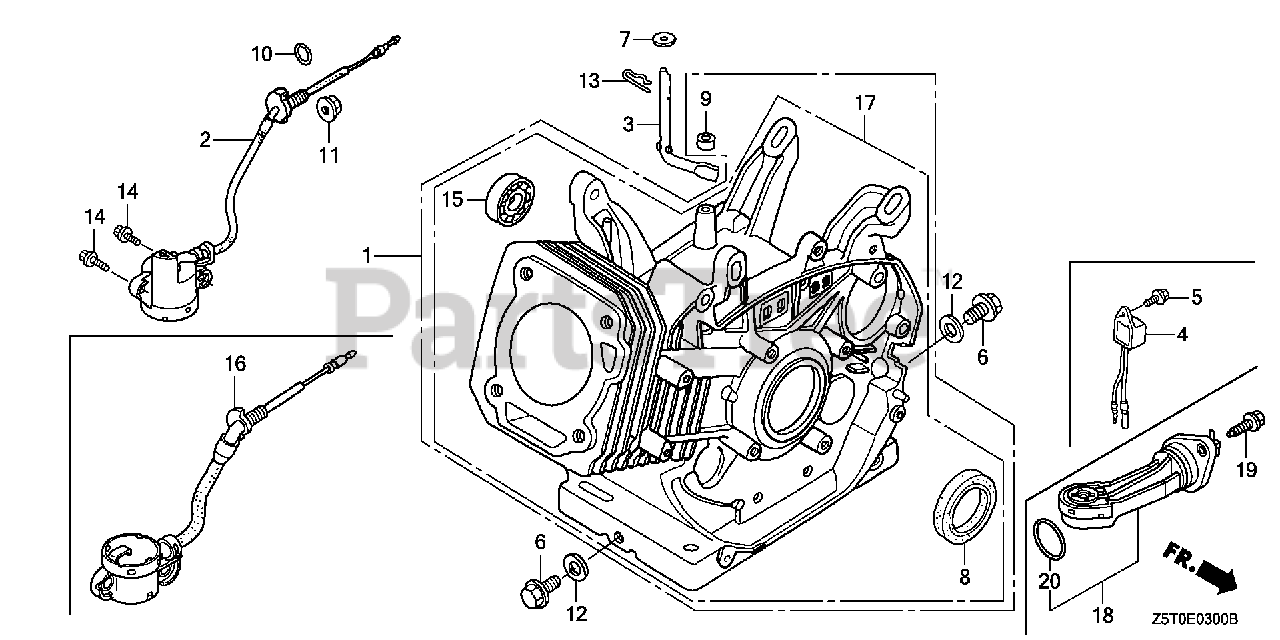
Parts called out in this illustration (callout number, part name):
1	CYLINDER ASSY. (ALERT)
3	SHAFT, GOVERNOR ARM
6	BOLT, DRAIN PLUG
7	WASHER (8.2X17X0.8)
8	OIL SEAL (35X52X8) (NOK)
9	OIL SEAL (8X14X5)
10	O-RING (14MM) (ARAI) Use up to Engine SN 2949254.
10	O-RING (14MM) (NOK)
11	NUT, FLANGE (10MM)
12	WASHER, DRAIN PLUG (12MM)
13	PIN, LOCK (10MM)
14	BOLT, FLANGE (6X12) Use up to Engine SN 1543277.
15	BEARING, RADIAL BALL (6202)
16	SWITCH ASSY., OIL LEVEL
